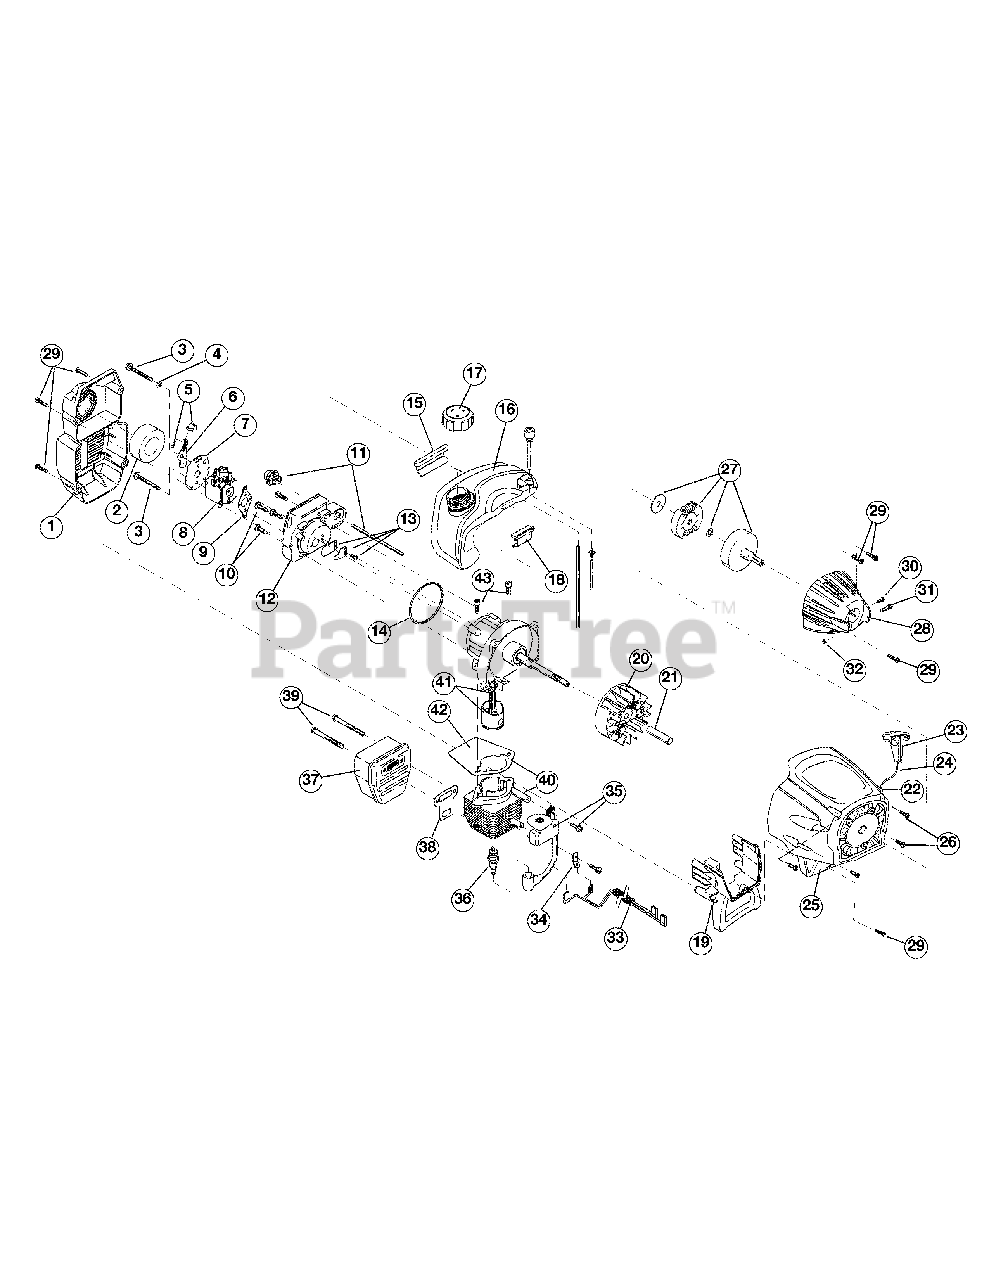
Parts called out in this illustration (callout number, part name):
1	Air Cleaner Cover Assembly
2	Air Cleaner Filter
3	Carburetor Mounting Screw Assembly
4	Wavey Washer
5	Choke Knob w/Screw
6	Choke Lever
7	Choke Plate
8	Carburetor Assembly
9	Carburetor Gasket
10	Carb Mount Screw
11	Primer & Hose Assembly
12	Carb Mount Assembly
13	Reed Assembly
15	Rear Mounting Pad
16	Fuel Tank Assembly
17	Fuel Cap Assembly
18	Front Mounting Pad
19	Shroud Extension & Stand
20	Flywheel Assembly
22	Rope Guide
23	Pull Handle
25	Starter Housing Assembly
26	Housing Screw
27	Clutch Rotor Assembly
28	Clutch Cover Assembly
29	Cover Screw
30	Anti-Rotation Screw
31	Clamping Screw
32	Clamping Nut
33	Wire Leads and Sleeve
34	Ground Tab
35	Module Assembly
37	Muffler Assembly
38	Exhaust Gasket
39	Muffler Mounting Bolts
40	Cylinder Assembly
41	Piston and Rod Assembly
42	Cylinder Gasket
43	Cylinder Bolt
